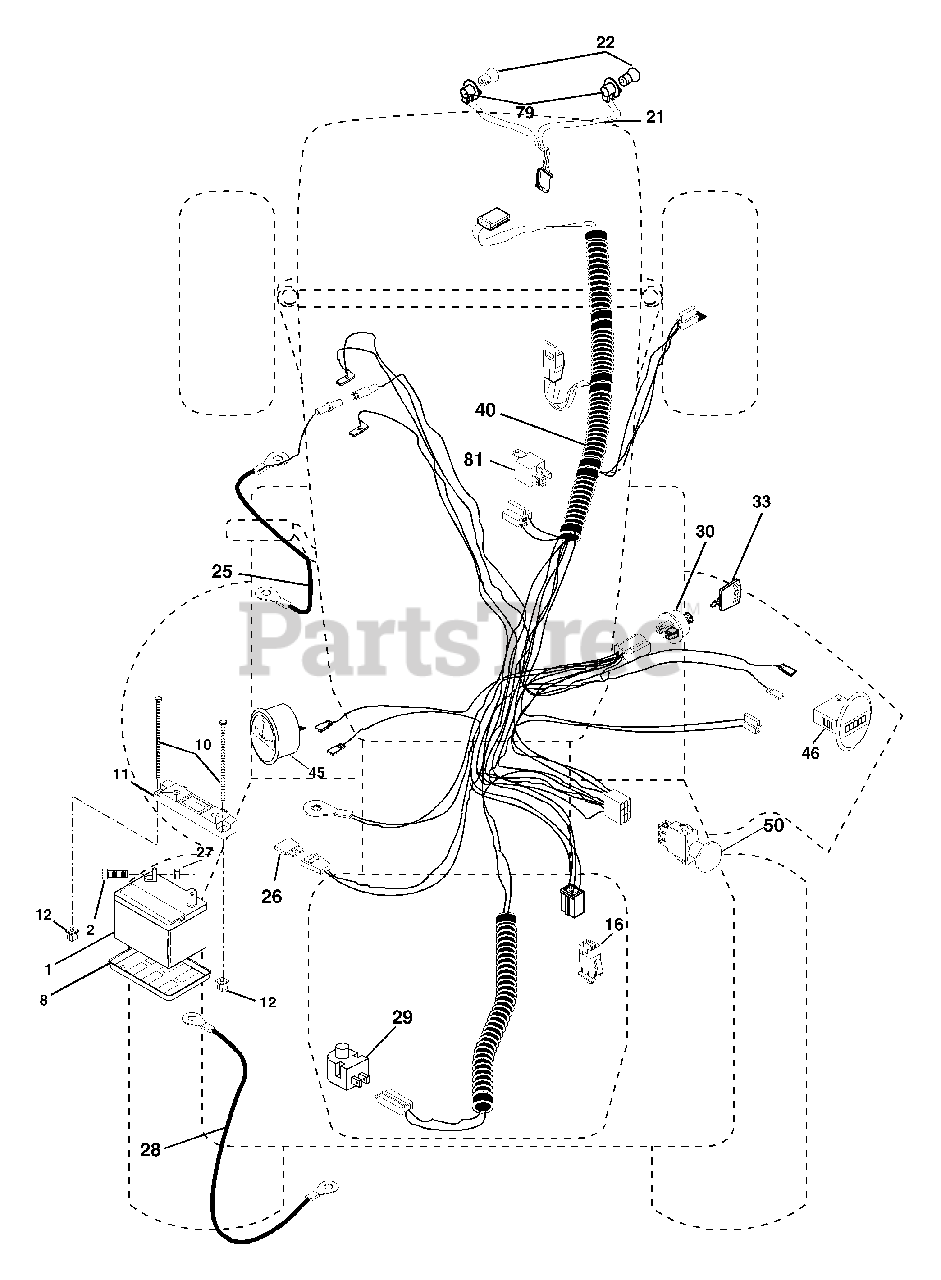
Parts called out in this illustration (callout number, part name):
1	Battery
2	Bolt Hex Head 1/4-20 x 3/4
8	Tray, Battery
10	Bolt, Battery Front 1/4-20 x 7.5 Zinc
11	Holddown Battery Front Mount
12	Nut, Push Nylon 1.4" Battery Front
16	Switch Interlock
21	Harness Socket Light w/4152J
22	Bulb Light
25	Cable, Battery
27	Nut Keps Hex 1/4-20
28	Cable, Ground
29	Switch, Plunger Normal Op Olive
30	Switch, Ign
40	Harness Ign.
42	Cover, Terminal Red
46	Hourmeter Snap-In
50	Switch, PTO
79	Bulbholder Asm
81	Relay Asm.
